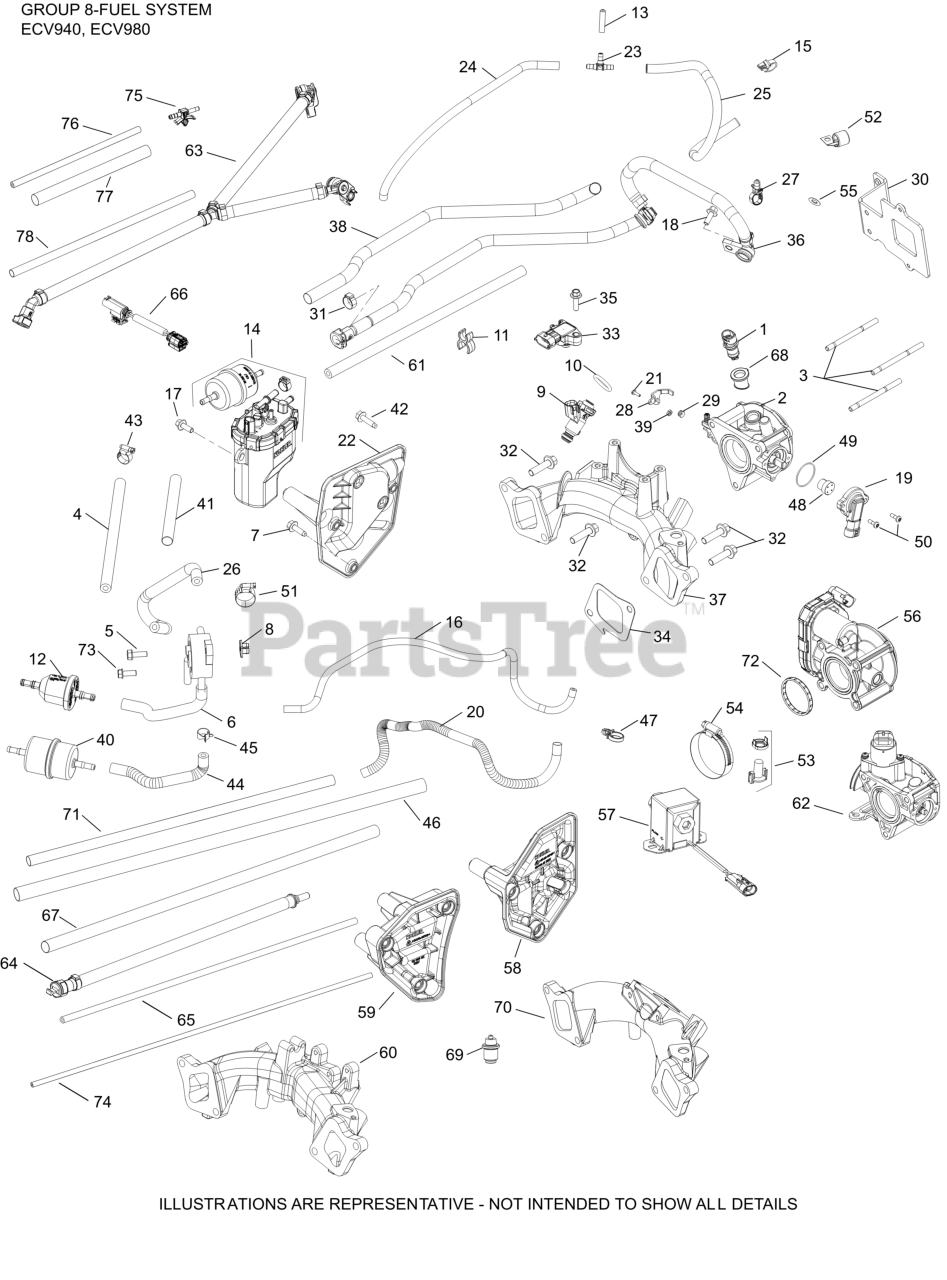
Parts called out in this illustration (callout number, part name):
4	LINE, FLEXIBLE FUEL
6	PUMP, FUEL
8	NUT, PLASTIC - BLACK
9	INJECTOR, FUEL
10	KIT, FUEL INJECTOR O-RING
11	RETAINER, CLIP
13	CAP, MASKING
14	KIT, FUEL PUMP MODULE
16	HOSE, EVAPORATIVE 20"- (#24326143S)
17	SCREW, FLG M6X1.0X16
22	BAFFLE, V/S FUEL PUMP MODULE
23	TEE CONNECTOR
26	HOSE, FUEL LINE
31	CLAMP, HOSE
31	CLAMP, OETIKER
32	SCREW, FLG M8X1.25X30
33	SENSOR, T-MAP
34	GASKET, INTAKE MANIFOLD
35	SCREW, FLG M6x1.0x20
36	RAIL, FUEL ASSEMBLY (COMMAND PRO 999)
38	SLEEVE, ANTI ABRASION
40	FILTER, FUEL
41	SLEEVE, ANTI ABRASION -USE 25 431 12-S
42	SCREW, THREAD FORMING
44	HOSE,LW PERM.FUEL 24.00"-USE 25 111 81-S
45	SPRING CLAMP, HOSE
46	SLEEVE, HEAT REFLECTIVE
47	CLIP, FUEL LINE
55	CLIP, RETAINER
56	BODY, ELECTRONIC THROTTLE ASM 34 DIA
70	MANIFOLD, INTAKE VERTICAL (ETB)
73	SCREW, HEX HEAD
75	CONNECTOR, EVAPORATIVE
76	HOSE, EVAPORATIVE
77	SLEEVE, ANTI ABRASION-USE 25 431 12-S
78	SLEEVE, ANTI ABRASION
